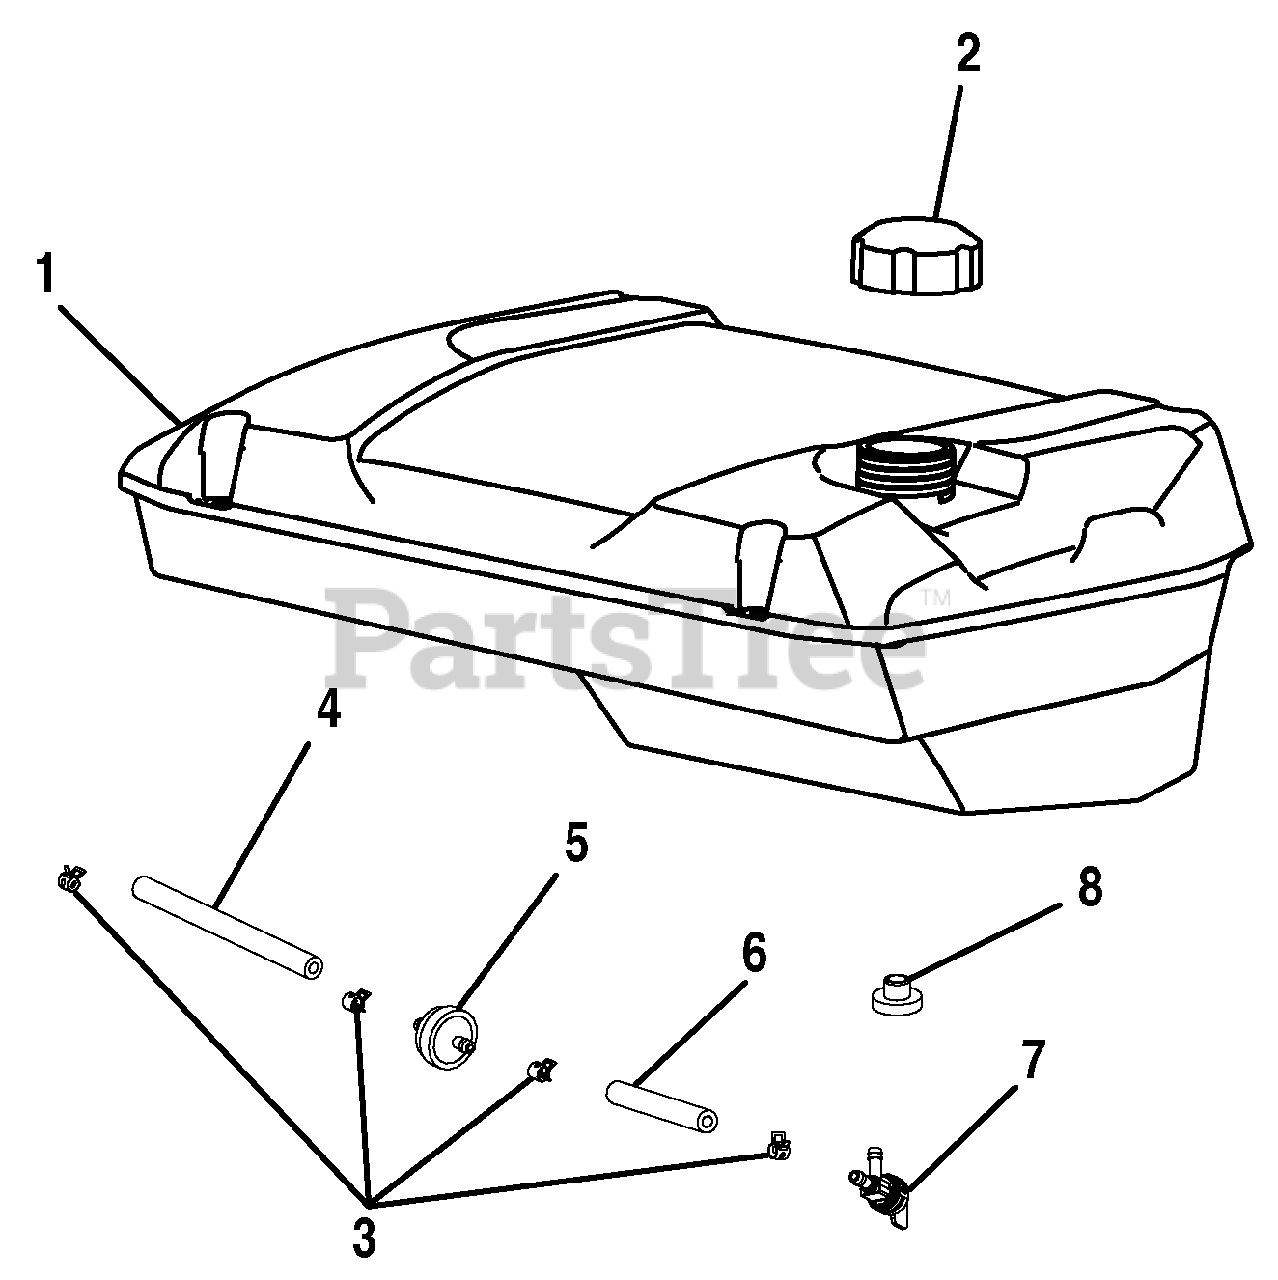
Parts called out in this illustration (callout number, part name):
1	Fuel Tank
2	Fuel Tank Cap
3	Fuel Line Clamp (1/2 in.)
4	Fuel Line (6.4 mm x 208 mm)
5	Fuel Filter
6	Fuel Line (6.4 mm x 105 mm)
7	Fuel Shut Off Valve
8	Fuel Line Bushing
